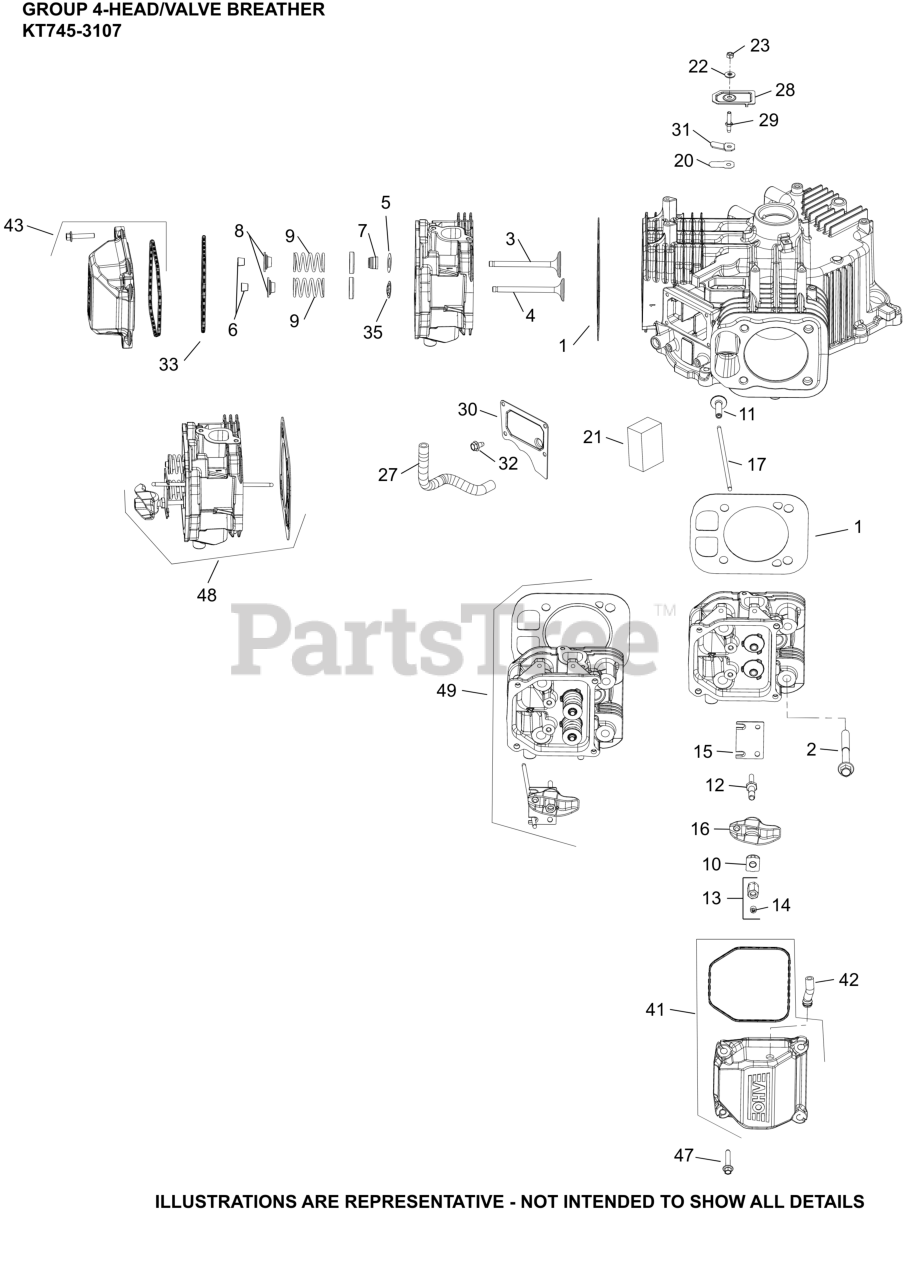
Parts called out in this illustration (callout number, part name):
1	KIT, CYLINDER HEAD GASKET
2	SCREW, HEX FLANGE M10 X 1.5-6g X 90mm
3	VALVE, INTAKE
3	VALVE, INTAKE (.25) - (#2401702S)
4	VALVE, EXHAUST
4	VALVE, EXHAUST (.25)
5	SPACER (.010")
6	KIT, RETAINER
7	SEAL, VALVE BAND
8	CAP, VALVE SPRING
9	SPRING VALVE
10	PIVOT, ROCKER ARM
12	STUD, ROCKER
13	HEX NUT ASSEMBLY
14	SCREW, SET
15	PLATE, GUIDE
16	ARM, ROCKER
17	ROD, PUSH
20	REED, BREATHER
21	FILTER, BREATHER
22	WASHER, SEALING
23	NUT, LOCK M5X.8
27	HOSE, BREATHER
28	COVER, BREATHER REED
30	COVER, BREATHER MEDIA
31	RETAINER, REED
32	SCREW, THREAD FORMING
33	O-RING (YELLOW), VALVE CO
35	RETAINER, VALVE GUIDE (KM)
41	KIT,BREATHER VALVE COVER (PLASTIC)
42	HOSE, FP-USE 32 326 07-S(PLASTIC COVERS)
43	KIT, VALVE COVER-PLAIN (PLASTIC)
47	SCREW, HEX FLANGE (M6 X 31.625 DOG PT)
48	KIT, #1 CYLINDER HEAD
49	KIT, #2 CYLINDER HEAD
